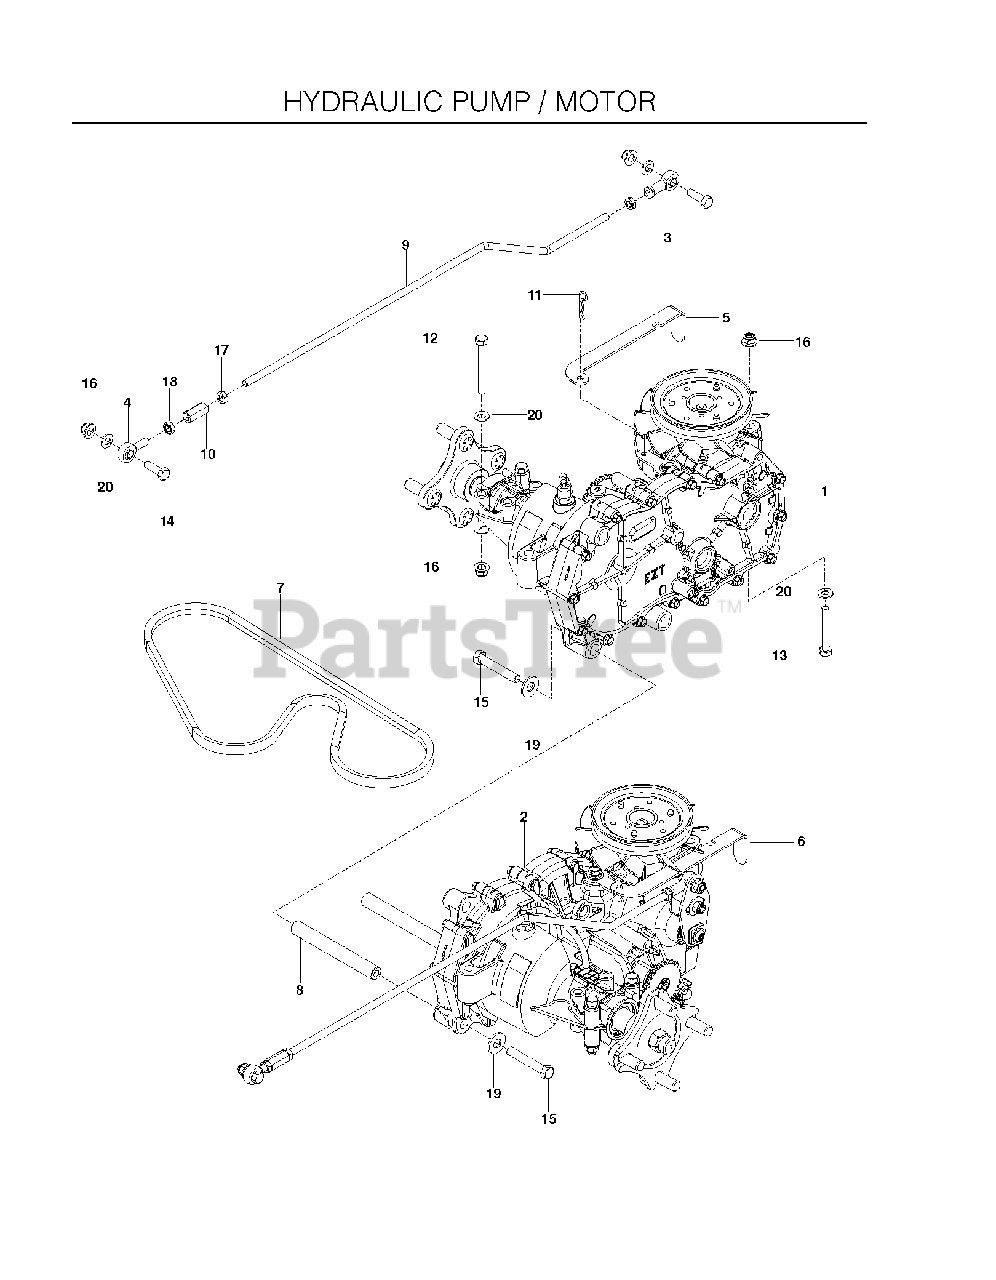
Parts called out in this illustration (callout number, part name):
1	HYDRO RH
2	HYDRO LH
3	RH ROD END
4	ROD END LH
5	RELEASE LEVER RH
6	RELEASE LEVER LH
7	BELT, EL 51.O4
8	SPACER, HYDRO
9	CONTROL ROD
10	ROD END COUPLER
11	HAIRPIN #2
12	HCS 5/16C X 2-3/4
13	CAPSCREW
14	HCS 5/16C X 1
15	HCS 3/8C X 2 1/4
16	5/16-18 NYLOC FLANGE NUT
17	NUT 5/16-24 UNF HEX JAM
18	NUT 5/16F LEFTHAND
19	WASHER 3/8 FLAT
20	FLAT WASHER 5/16 SAE
